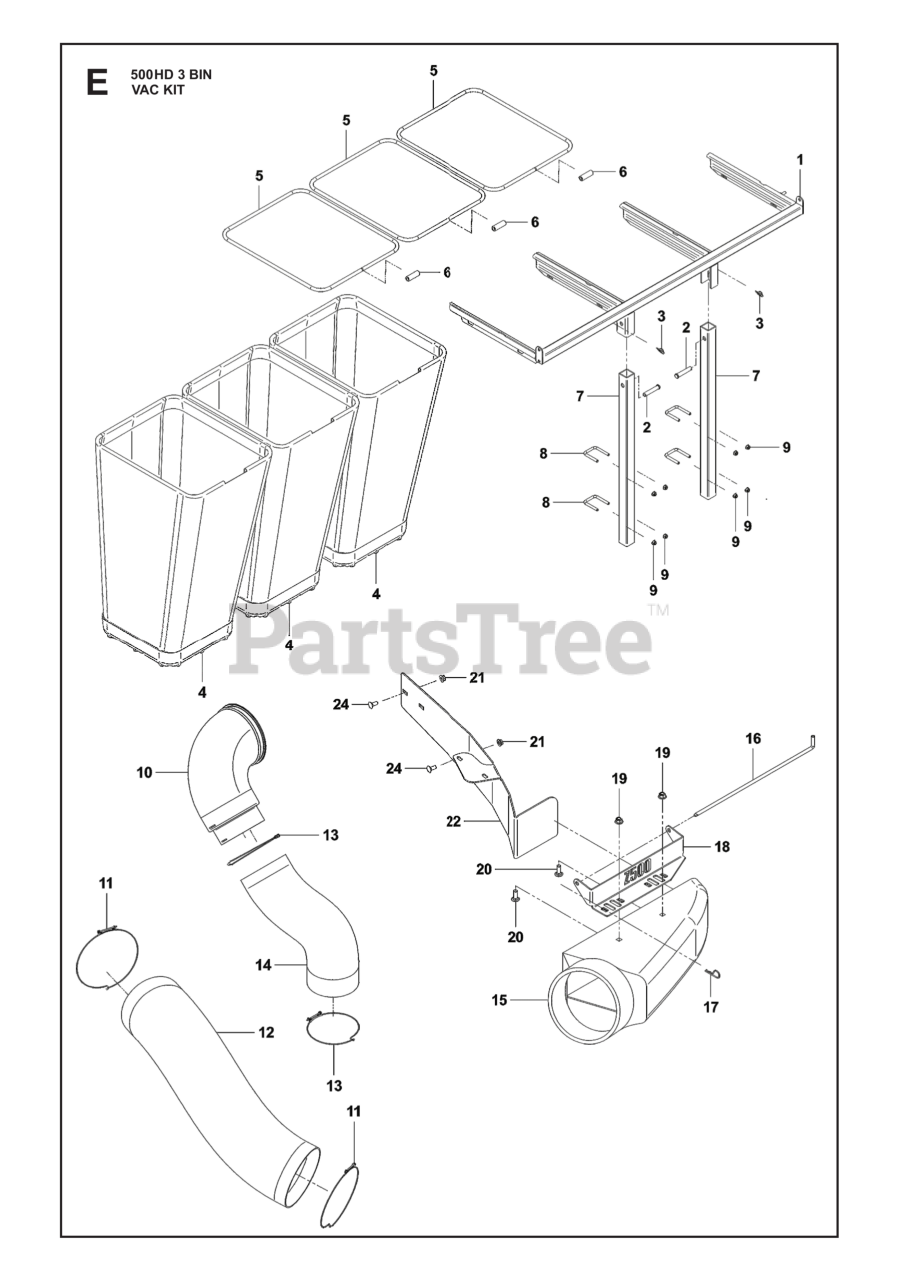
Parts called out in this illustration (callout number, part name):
5	SUPPORTS
6	CONNECTORS
7	FRAMES
9	NUT HEXAGON FLANGE 5/16-18 ST
21	NUT HEXAGON FLANGE 5/16-18 ST
